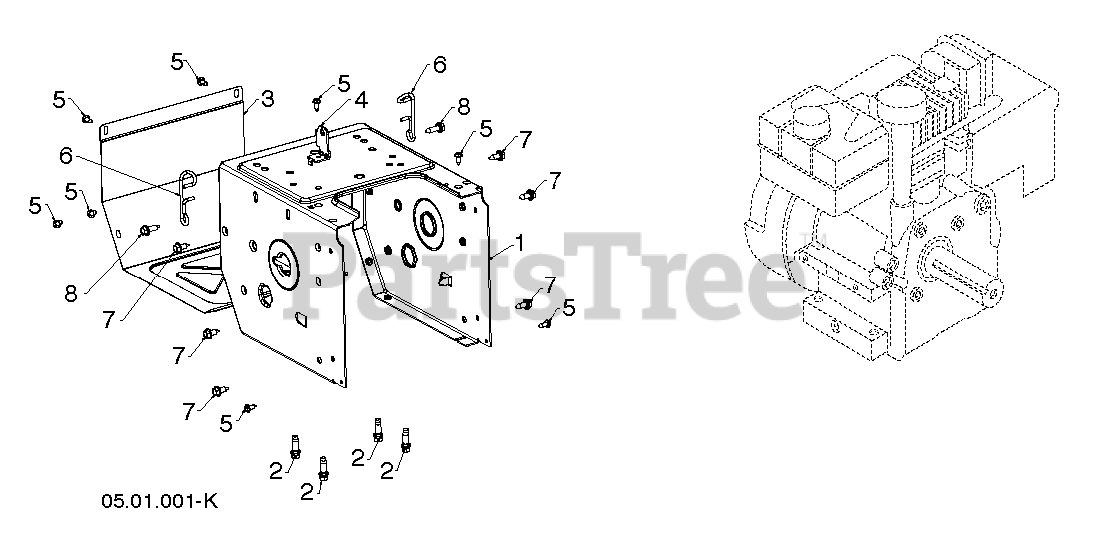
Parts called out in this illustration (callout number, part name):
1	FRAME.GEAR.CASE.ORANGE
2	BOLT 3/8-16X1-1/8
3	COVER COVER.FRAME MS668 ORANGE
4	BRACKET.SHIFTER.BZP
5	SCREW.HEX HEAD W/COLLAR 1/4-20
6	WIREFORM.SUPPORT.CABLE
7	BOLT.HEX.HD.WASHER.5/16-18X.75
8	SCREW HEXAGON HEAD WITH COLLAR
